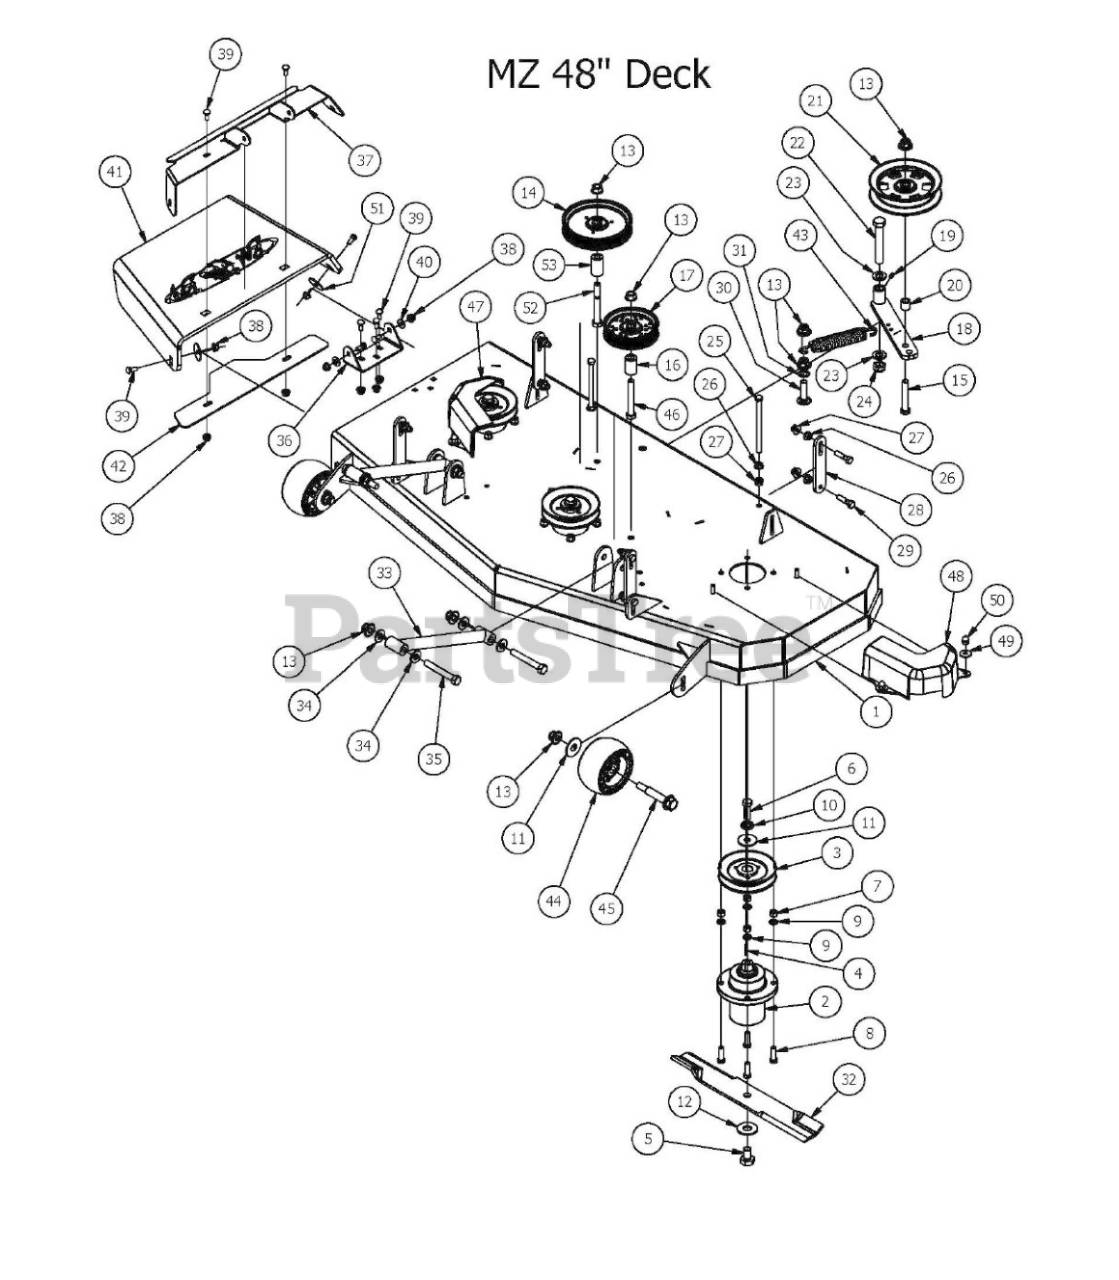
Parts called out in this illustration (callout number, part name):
1	2017 48" MZ Deck-Welded Shell
3	MZ Deck Pulley
4	3/16 x 1 Square Key
5	5/8" x 1 1/2" Grade 8 Hex Bolt (Fine)
6	1/2"-20 x 1 1/2 - Grade 5 Fine Thread Bolt
7	3/8" Hex Nut
8	3/8" x 1 1/4" Hex Bolt
9	3/8" Lock Washer
10	1/2" Lock Washer Zinc
11	1/2" Belleville Washer
12	5/8" Flat Washer
13	1/2-13 Nylon Insert Flange Washer
14	5-3/4 Idler Pulley-Capitol Stampings
15	1/2-13 x GR 5 Hex Bolt Zinc
16	Idler Pulley Standoff
17	4 3/4 Idler Pulley - ABFI-76
18	Deck Idler
19	1/4" Press in Grease Fitting
20	Spacer 3/4 OD x 1/2 ID x 3\4 Length
21	5" Idler Pully
22	5/8" x 4" Hex Bolt
23	.630 ID Plastic Washer
24	5/8-11 Nylon Insert Jam Half Nut
25	3/8-16 x 5 1/2 Hex Bolt
26	3/8" Flange Nut
27	3/8 Nylock Flange Nut
28	2017 MZ/ZT Deck Hanger
29	3/8" x 1 1/2" Hex Bolt
30	1/2 x 2" Carriage Bolt
31	.517 Square Hole Round Washer
32	48" High Lift Fusion Blade
33	MZ/ZT Deck Locator
34	.505 Nylon Spacer
35	1/2-13 x 3 1/2 GR 5 Hex Bolt
36	Chute Hanger 48 MZ
37	Discharge Chute Bracket 48 MZ (Upper)
38	5/16" Nylon Flange Nut
39	5/16-18x3/4 carriage bolt
40	.360 ID Plastic Washer
41	Rubber Discharge Chute MZ (Component)
42	2017 MZ Discharge Chute Bracket-Lower
43	2015 Deck Idler Spring
44	Deck Wheel
45	Deck Wheel Bolt
46	1/2 x 3 1/2 Flange Bolt Grade 8
47	pulley cover chute side
48	pulley cover non-chute side
49	.360 ID Plastic Washer-Black
50	Acorn nut-pulley Cover
51	5/16" Fender Washer
52	1/2" x 4" Bolt (Grade 8)
53	1 3/4" Pulley Spacer
